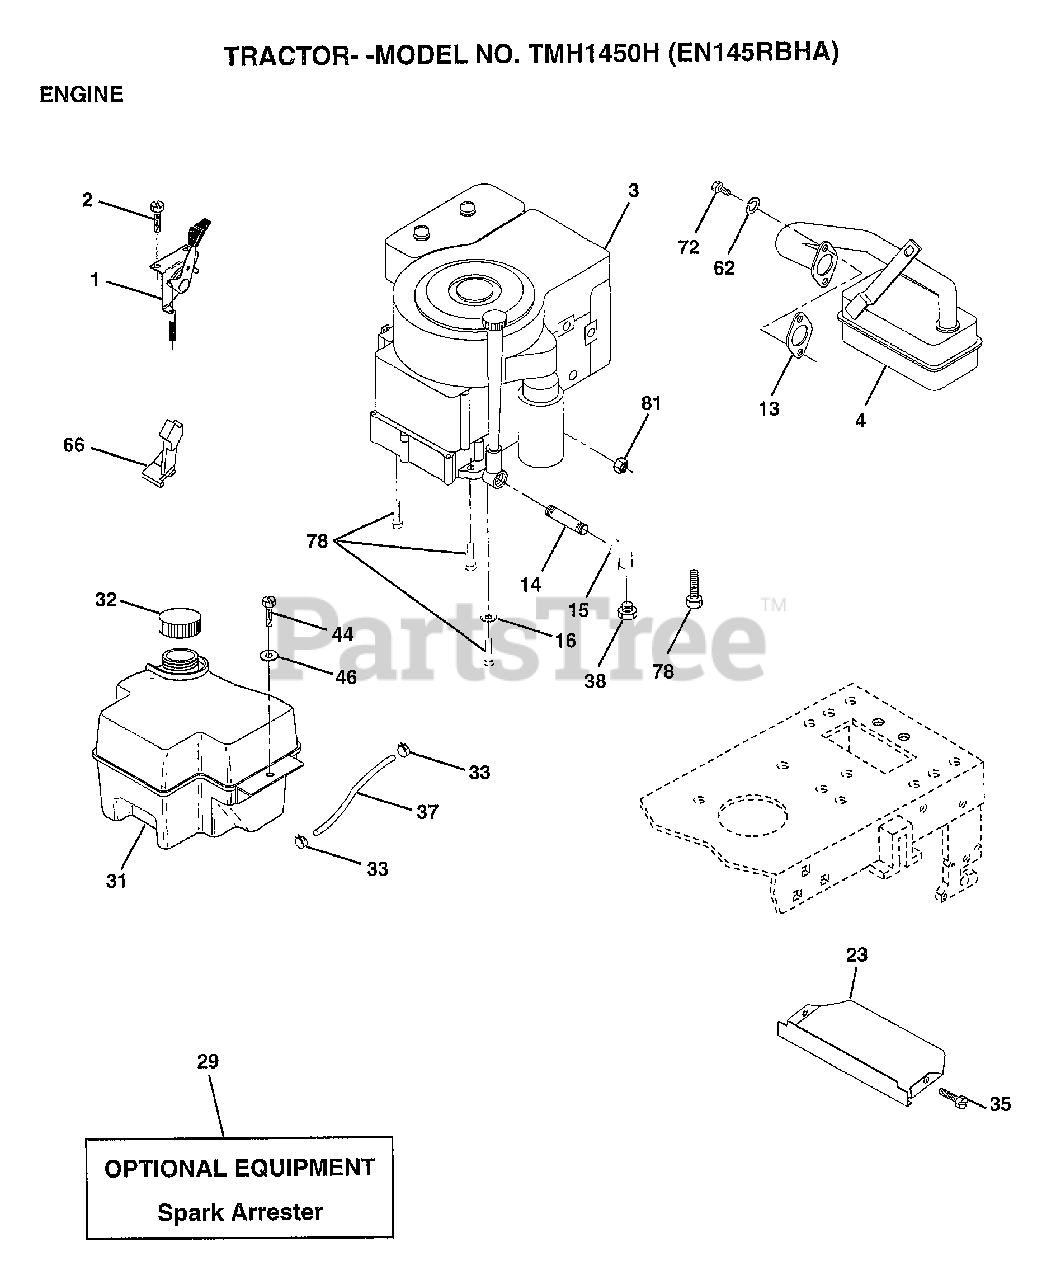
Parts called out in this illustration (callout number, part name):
1	CONTROL.THTL.23.5
2	SCREW LT
4	MUFFLER
14	PIPE NIPPLE
15	ELBOW
16	LOCKWASHER
23	SHIELD.BRN/DBR.GD
31	TANK.FUEL.LT.
32	CAP ASM FUEL
33	HOSE CLAMP
35	SCREW
37	LINE FUEL
44	SCREW HEX CRT
46	WASHER
62	LOCKWASHER
66	"STOP,DASH THROTT"
72	SCREW
78	SCREW
81	NUT
